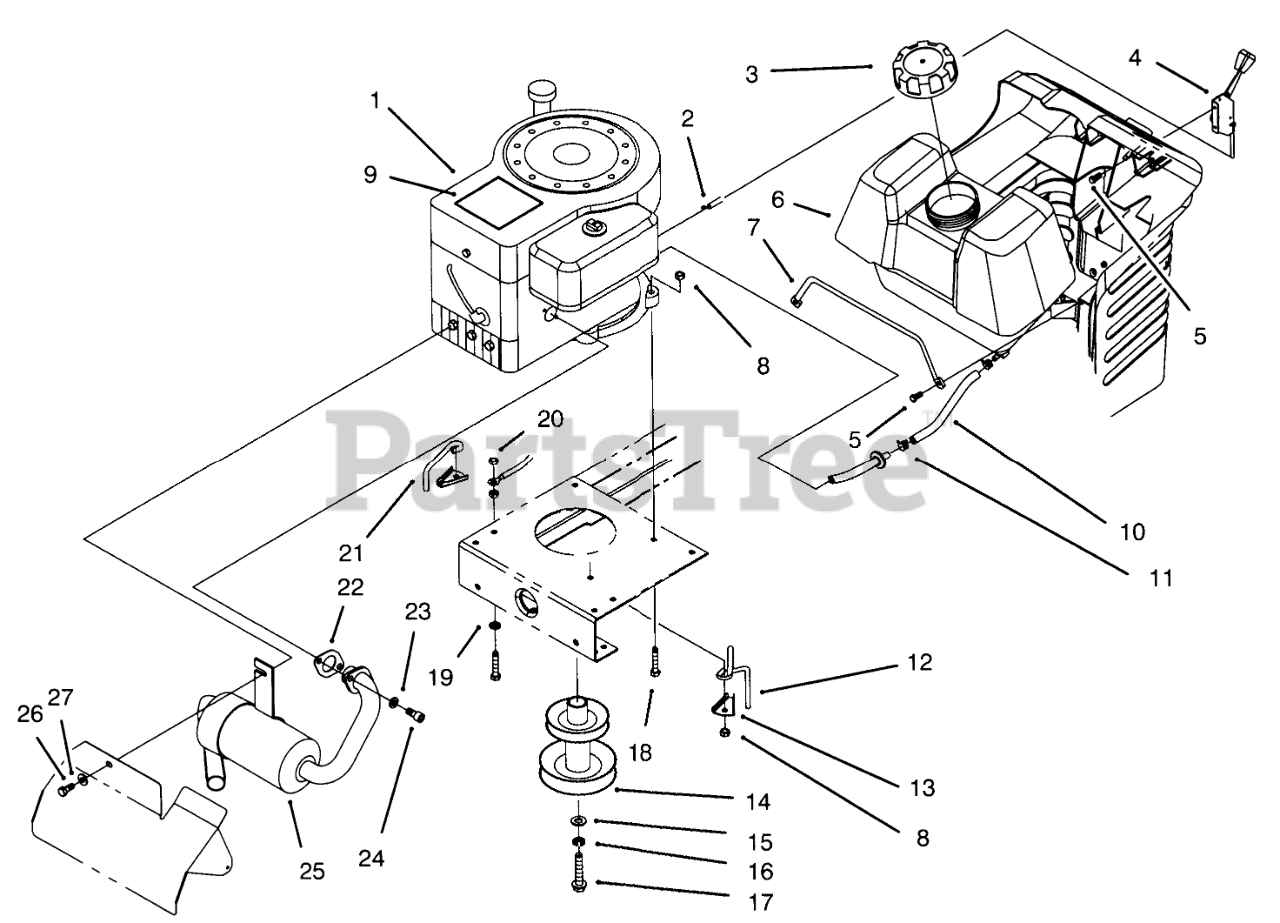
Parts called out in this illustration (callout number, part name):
1	Engine-12 H.P. (Model No. 71182 Only)
2	THROTTLE CABLE ASM
3	GAS CAP ASM
4	THROTTLE CONTROL ASM
5	SCREW-SPECIAL
6	GAS TANK ASM
7	GAS TANK ROD
8	NUT-LOCK, NI
9	DECAL - ENGINE
10	HOSE-FUEL
11	CLAMP-HOSE
12	GUIDE-BELT, LH
13	ANCHOR-GUIDE, BELT
14	PULLEY-ENGINE
15	WASHER-FLAT
16	WASHER-LOCK
17	SCREW-HH
18	SCREW-HH
19	WASHER-LOCK
20	NUT-KEPS
21	GUIDE-BELT, RH
22	GASKET-EXHAUST
23	WASHER-LOCK
24	SCREW-HSH
25	MUFFLER
26	SCREW-HH
27	WASHER-LOCK
